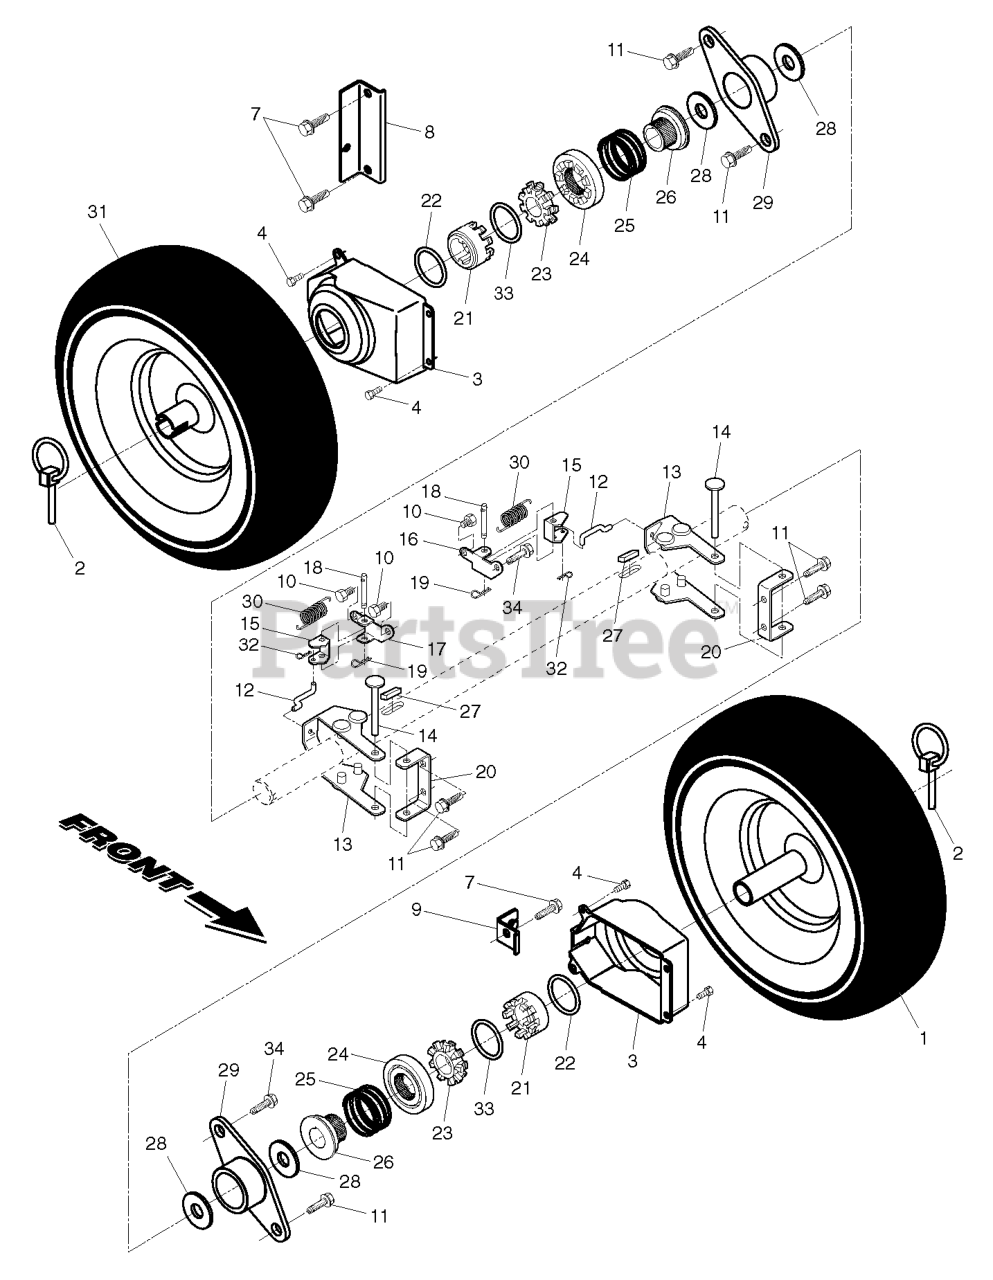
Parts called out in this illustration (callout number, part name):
1	16 X 4.8 LH WHEEL GREY
2	PIN KLIK, 1/4
3	COVER, POWER STEERING
4	SCREW, HEX HEAD, TAPPING
7	SCREW 3/8-16X1
8	BRACKET, STEERING CABLE RH
9	BRACKET, STEERING CABLE LH
10	SCREW 1/4X20
11	SCREW, HEX HEAD 5/16-18 X 1/2
12	LINK, STEERING LEVER
13	YOKE, STEERING
14	PIN, STEERING LEVER
15	BELLCRANK.STEER
16	BRACKET.STEER.PIVOT.LH.YZ
17	BRKT.STEER.PIVOT.RH
18	PIN, STEERING BELLCRANK
19	RETAINER CLIP PM
20	BRACKET.STEER.PNT.BLACK
21	RP.DRIVER WHEEL
22	RING, WIRE RETAINER
23	LOBE WHEEL
24	RP.SLIDE.CLUTCH
25	SPRING, CLUTCH SLIDE
26	RP.LOBE.AXLE
27	KEY, SQUARE 1/4 X .875
28	WASHER TRUST 1"
29	BEARING, AXLE
30	SPRING LATCH
31	16 X 4.8 RH WHEEL
32	RETAINER CLIP
